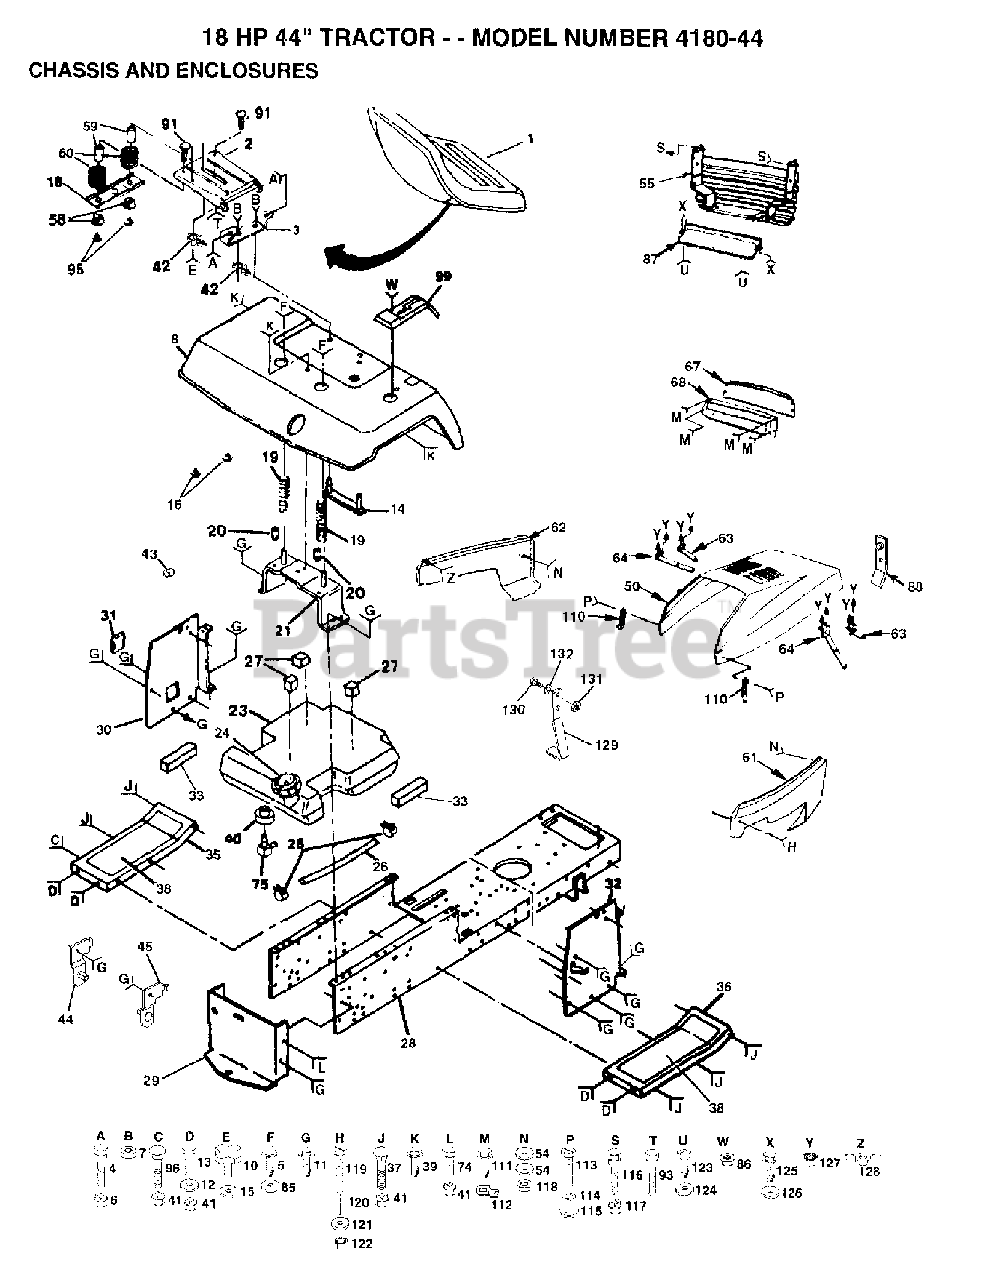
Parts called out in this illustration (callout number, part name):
2	PAN SEAT
3	BRKT,SEAT PIVOT**
4	BOLT, SHOULDER LT
5	SCREW LT
6	LOCKNUT
7	LOCKNUT
8	Poulan TBD
12	WASHER
14	STRAP-FENDER YT
16	CAP SPRING
18	BRKT SWITCH
19	SPRING COMPRESSION
20	NUT-PUSH YT
21	FENDER BRKT
23	FUEL TANK LT
25	HOSE CLAMP
26	FUEL LINE
27	PAD-SPACER LT
28	CHASSIS
29	DRAW BAR
31	COVER ACCESS
33	PAD IDLER TI
35	FOOTREST LH**
36	FOOTREST RH
38	FOOTREST PAD
39	SCREW LT
40	BUSHING OUTLET T
41	NUT
42	INSULATED CLIP
44	BRACKET LH PIVOT
45	BRACKET RH PIVOT
50	Poulan TBD
54	WASHER PM
59	SPACER SPLIT
60	SPRING COMPRESSED
61	Poulan TBD
62	Poulan TBD
75	STEM FUEL TANK
86	NUT.PUSH.3/16
87	Poulan TBD
91	BOLT CARRIAGE 1/4-20X1 3/8
93	BOLT, SHOULDER**
95	NUT T
110	LATCH.HOOD.
113	SCREW
114	LOCKWASHER
115	NUT.WELD
116	Bolt
117	NUT.CROWNLOCK.1/4
118	NUT
119	SCREW
120	SPACER LT
121	WASHER
122	NUT **
123	Screw, Lt
124	WASHER
125	SCREW HEX CRT
126	WASHER
127	NUT
128	WING NUT
129	MOWER STOP
131	NUT
132	WASHER GT
